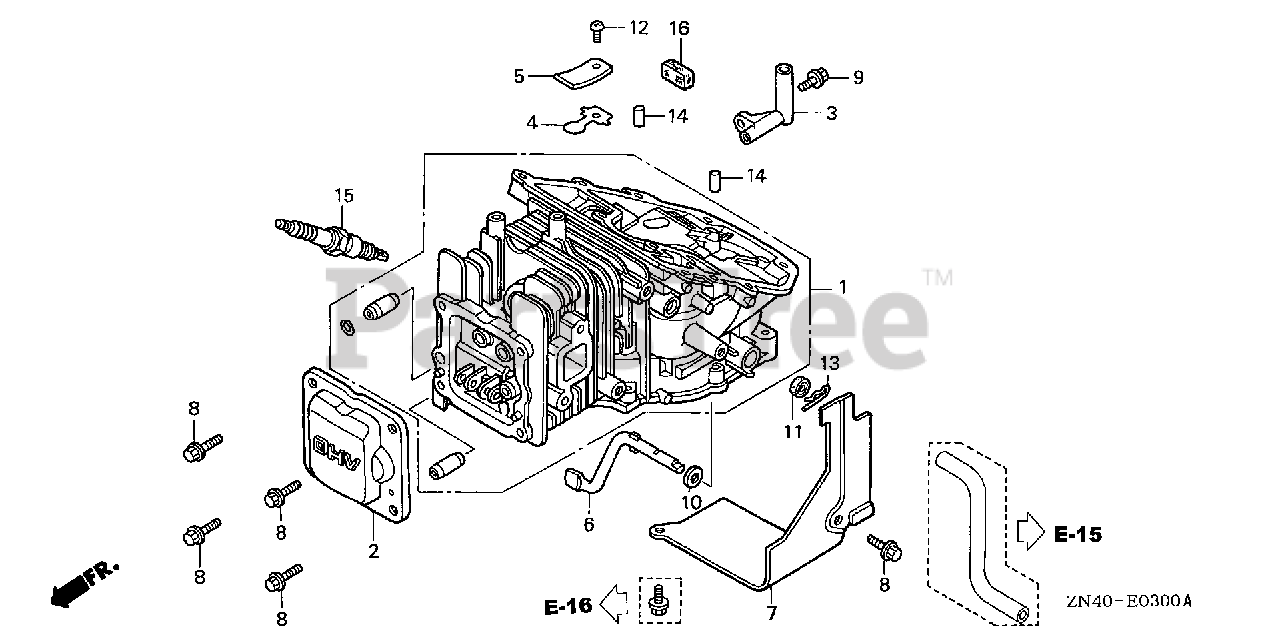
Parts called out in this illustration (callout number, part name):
2	COVER, HEAD
3	PIPE, BREATHER
4	VALVE, OIL OUTLET
5	PLATE, STOPPER
6	SHAFT, GOVERNOR ARM
8	BOLT, FLANGE (5X12)
9	BOLT (4X10)
10	WASHER (5.2X9)
11	OIL SEAL (5X11X5)
12	SCREW, PAN (3X5)
13	PIN, LOCK (6MM)
14	ROLLER (6X15)
15	SPARK PLUG (U14FSR-UB)
15	SPARK PLUG (CR4HSB)
15	SPARK PLUG (U16FSR-UB)
15	SPARK PLUG (CR5HSB)
16	FILTER, BREATHER
